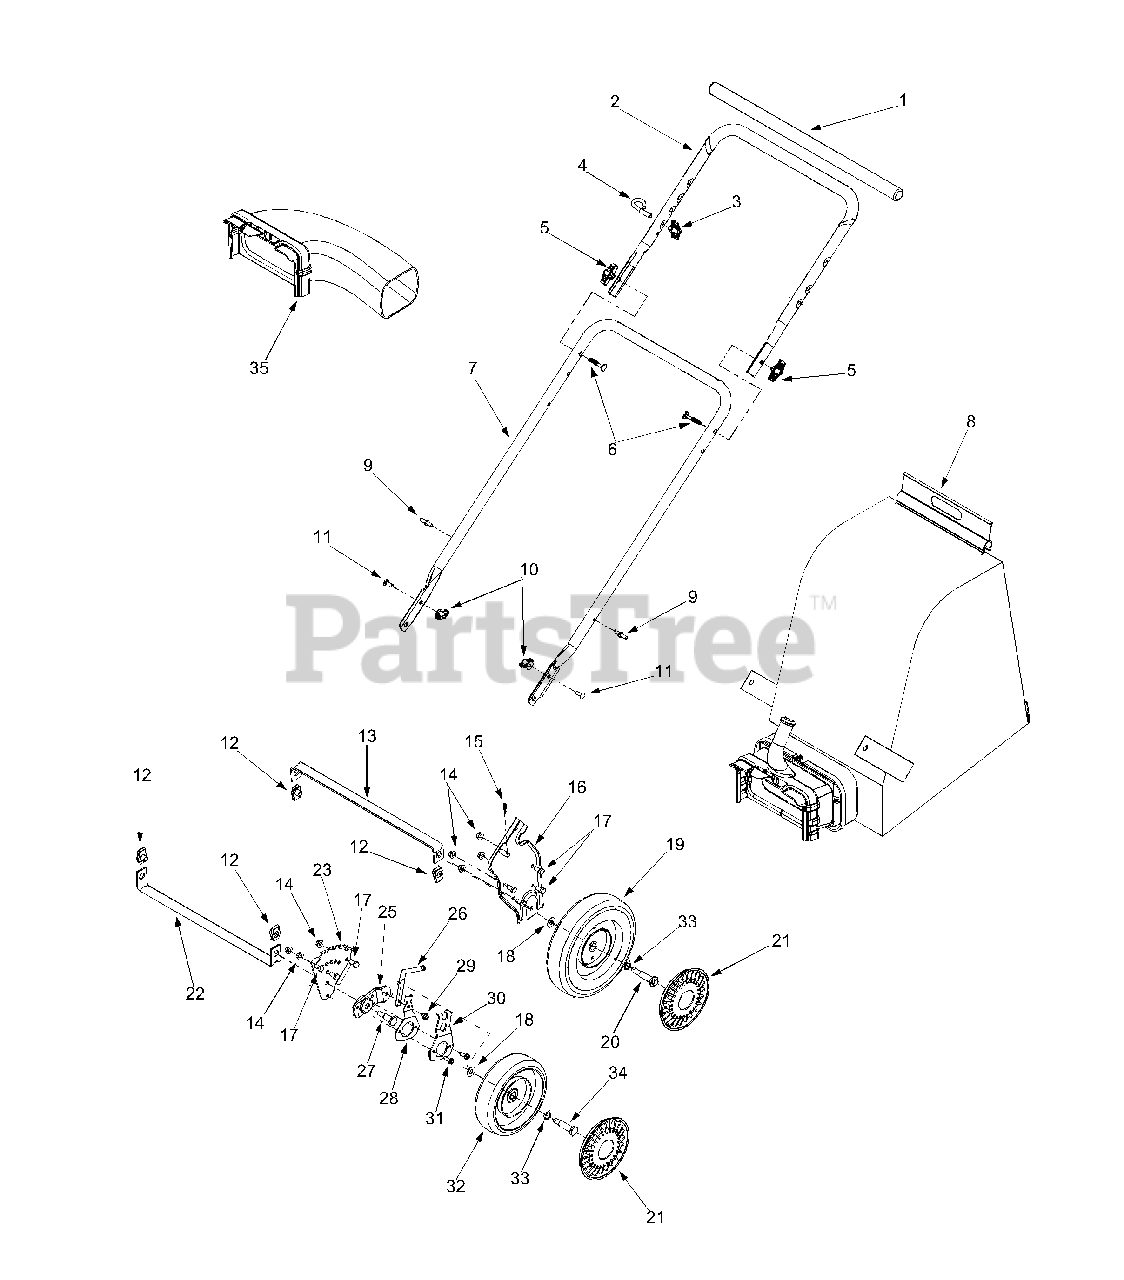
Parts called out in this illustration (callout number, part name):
1	Foam Grip
2	Upper Handle
4	Eye Bolt
5	Handle Knob 5/16-18
6	Carriage Bolt
8	Bag Assembly
9	Studs
10	Wing Nut 1/4-20
11	Carriage Screw 1/4-20 x .75
12	Lock U-Clip Nut 3/8-16
15	Cotter Pin
17	Hex Cap Screw 5/16-18 x .625
18	Bell Washer.401 ID x.870 OD
19	Wheel 9 x 2
20	Shoulder Screw 3/8-16
21	Hubcap
22	Front Wheel Support Brace
23	Hgt Bracket Adjuster LH
26	Handle Height Adjuster
27	Shoulder Screw 3/8-16
28	Height Adjuster Plate Spring
29	Hex Washer Screw 1/4-20 x .375
32	Wheel 8 x 2
33	Wave Washer .531 ID x .781 OD
34	Shoulder Screw
35	Blower Chute Assembly
